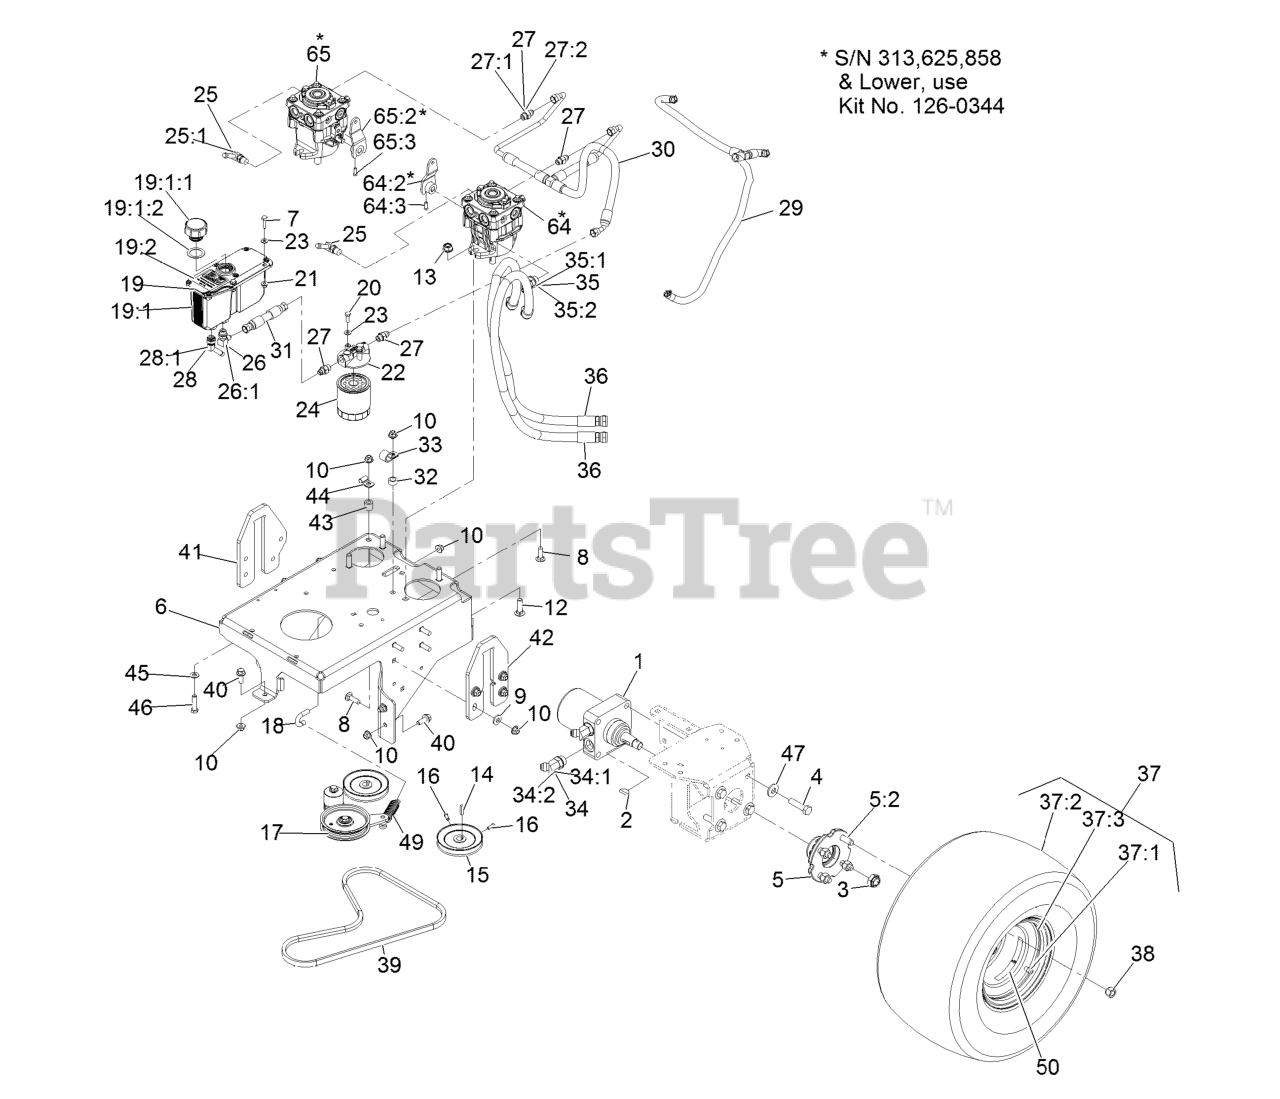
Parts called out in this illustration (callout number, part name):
1	MOTOR, WHEEL TE230
2	KEY-WOODRUFF
3	NUT-LOCK
4	SCREW-HH
5	WHEEL HUB ASM
5:2	STUD-TYPE, DRIVE
6	WELDMENT, FRAME
7	SCREW-HH
8	BOLT-CARR
9	WASHER-BELLEVILLE
10	NUT-HF, NI
12	SCREW-HH
13	NUT-HF, NI
15	PULLEY-PUMP
16	SCREW-SET
17	PUMP IDLER ASM
18	ANCHOR, SPRING
19	RESERVOIR ASM
19:1	Reservoir-Hyd
19:1:1	Cap-Reservoir, HYD
19:1:2	GASKET-CAP
19:2	DECAL-HYDRAULIC TANK
20	SCREW-HH
21	NUT-HHF
22	HEAD-FILTER
23	WASHER-FLAT
24	FILTER-25 MICRON, BI-DIRE
25	FITTING-ELBOW, 90
25:1	O-RING
26	FITTING-ELBOW, 90 DEG
27	FITTING-STRAIGHT
28	FITTING-BARBED, 45 DEG
28:1	O-RING
29	HOSE ASM-HYD LP 3/8
30	HOSE ASSEMBLY - CHARGE
31	HYD HOSE ASM
32	SPACER-WHEEL
33	CLIP-LOOM
34	FITTING-HYD, 45 DEG
35	FITTING-HYD, 45 DEG
36	HYD HOSE ASM
37	WHEEL/TIRE ASM
37:1	RIM-8 INCH
37:3	Stem-Valve
38	NUT-LUG
39	BELT-V, LOWER PTO
40	SCREW-HHF 3/8-16 X 1
41	PLATE-LIFT, RH
42	PLATE, LIFT LH
44	CLIP-TUBE
45	WASHER-FLAT
46	SCREW-HH
47	WASHER-SPRING
49	SPRING-EXTENSION
64	PUMP W/ARM - LEFT
64:2	ARM-HYDRO
64:3	SCREW-SET
65	PUMP W/ARM -RIGHT
65:2	ARM-HYDRO
65:3	SCREW-SET
